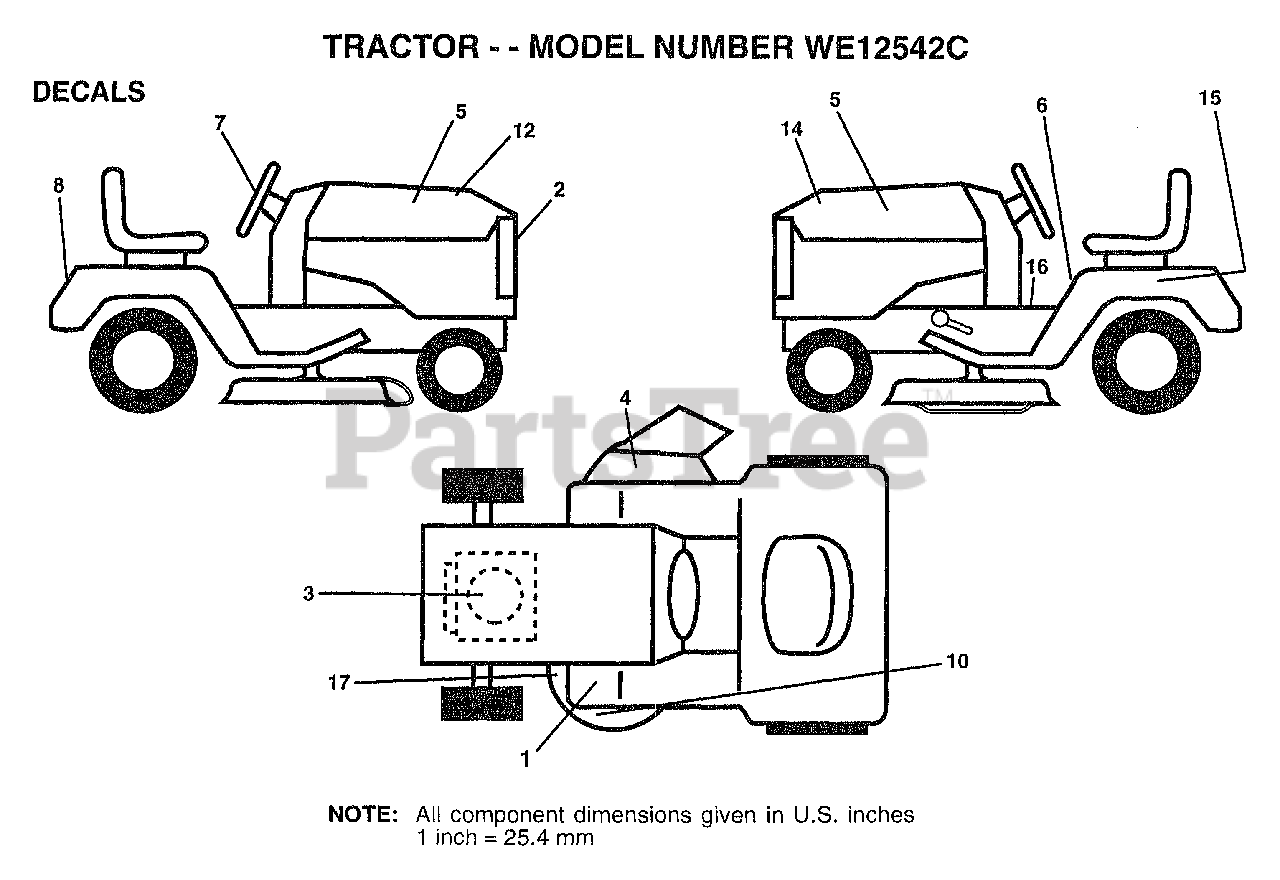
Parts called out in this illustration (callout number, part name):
1	DECAL T
2	DECAL, GRILLE LENS
3	DECAL, HP ENGINE
4	"DECAL, WARNING"
5	DECA, PNL SD
6	DECAL.CAUT.ENG/FR
7	DECAL, INS STRG WH
8	DECAL.FENDER.LOGO
10	DECAL, DECK GRASSEATER
12	DECAL.HOOD.RH.
14	DECAL.HOOD.LH
15	DECAL.BATRY.3-3908
16	"DECAL.OPER,SDL"
17	"DECAL-SCHEM,BELT"
